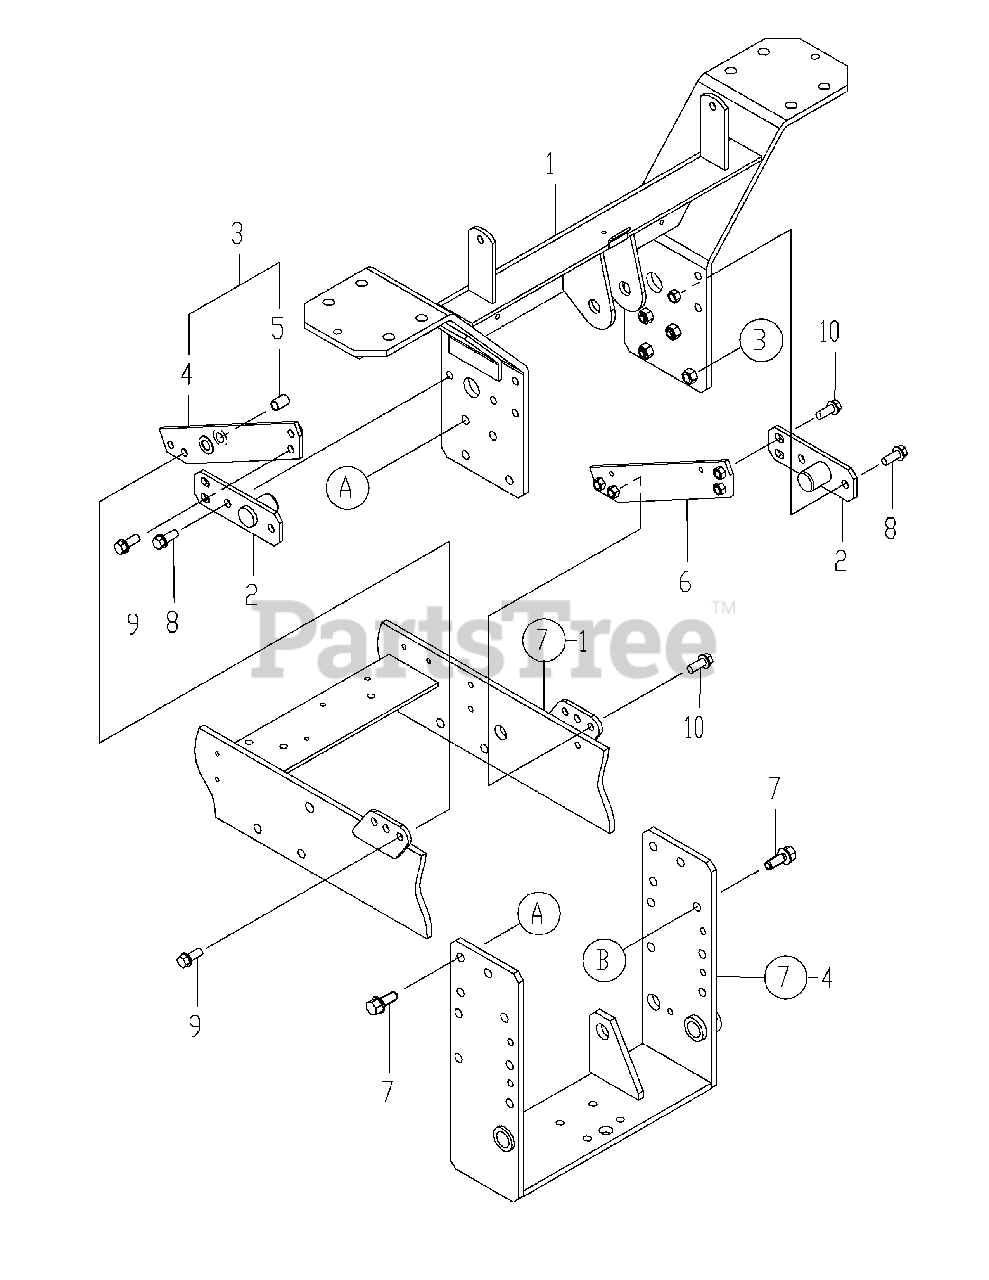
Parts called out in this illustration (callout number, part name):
1	LOWER FRAME CMP
2	PLATE, SIDE CMP
3	FRAME L, JOINT ASSY
4	FRAME L, JOINT CMP
5	BEARING, 12 X 20
6	FRAME R,JOINT CMP
